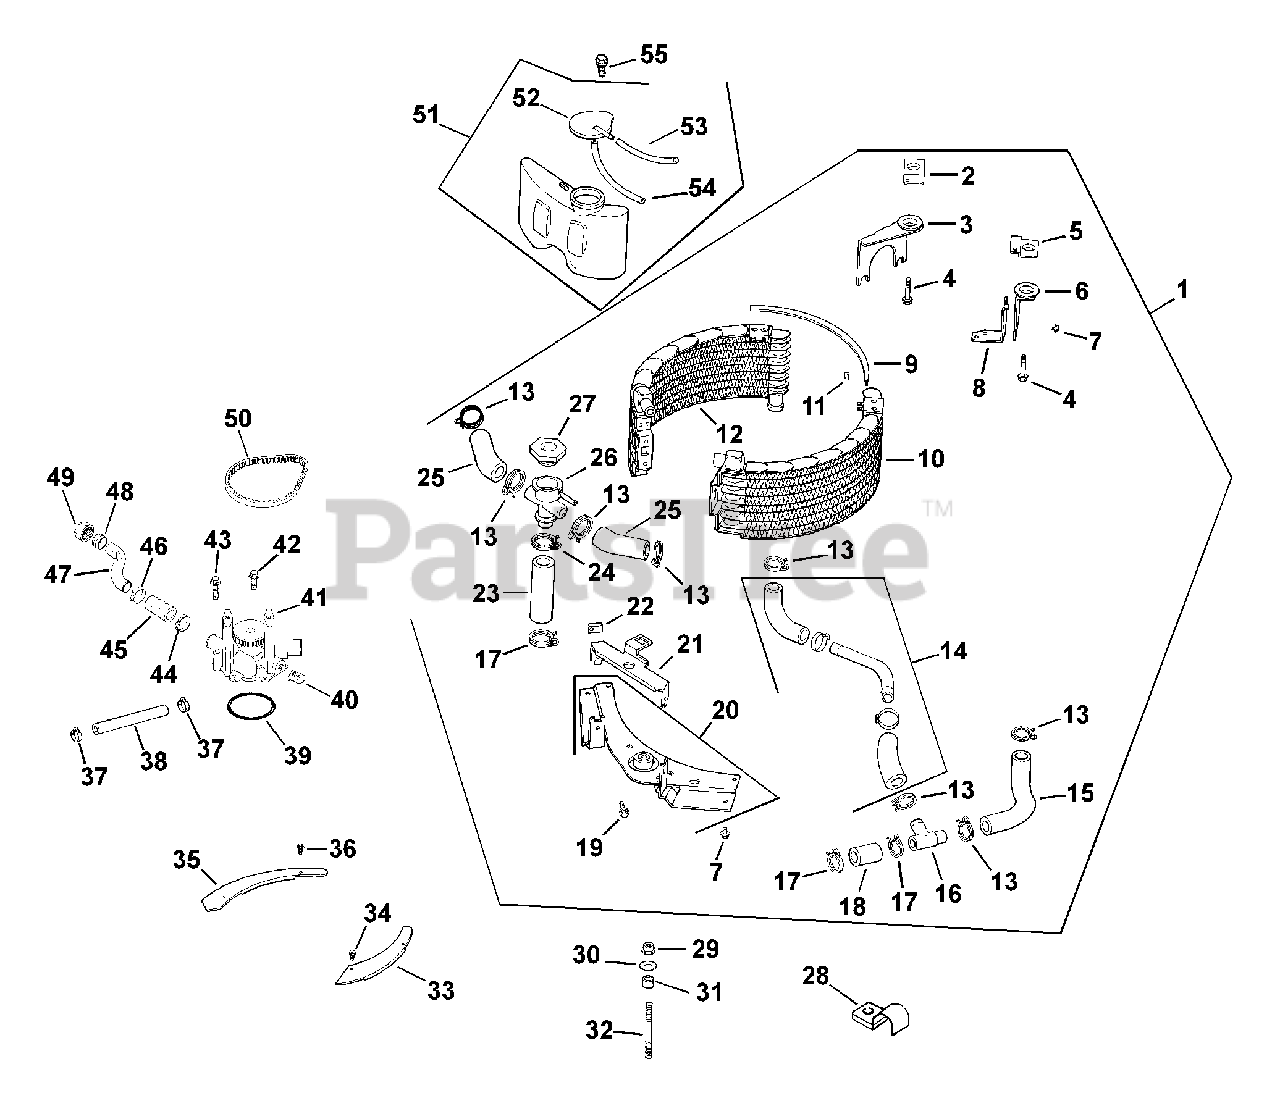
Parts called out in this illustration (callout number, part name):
1	RADIATOR ASSEMBLY - DISCONTINUED
2	BRACKET, LEFT KIDNEY
3	BRACKET, SOLENOID ATTACHING
4	SCREW, RADIATOR ISOLATOR
5	BRACKET, RIGHT KIDNEY
6	BRACKET, UPPER Z ATTACHING
7	SCREW, FLG M6X1.0X10
8	BRACKET, LOWER Z ATTACHING
9	TOP TIE BAR
10	RADIATOR CORE - (#DSC)
11	NUT, LOCK M6X1.0
12	RADIATOR CORE-DISCONTINUED
14	HOSE, OUTLET - (#DSC)
15	HOSE, OUTLET - (#DSC)
16	TEE, HOSE CONNECTOR (#DSC)
17	CLAMP, THERMOSTAT HSG OUTLET
18	HOSE, OUTLET
19	SCREW, FLG M6X1.0X16
20	BRACKET, BOTTOM ATTACHING
21	BRACKET, TOP ATTACHING
22	U CLIP - DISCONTINUED
23	HOSE, INLET - (#DSC)
24	CLAMP - DISCONTINUED
25	HOSE, INLET-DISCONTINUED
26	FILLER NECK - (#DSC)
27	CAP, RADIATOR - (#6617309S)
28	CLIP,LWR RADIATOR HOSE HALF-DISC.
29	NUT, LOCK M6X1.0
30	WASHER, FLAT 1/4"
31	SLEEVE, INTAKE MANIFOLD - DISC.
32	STUD, M6X1.0X53 - DISCONTINUED
33	PLATE, LEFT BLOCK OFF
34	SCREW, CAP M6X1.0X10
35	PLATE, RIGHT BLOCK OFF - DISC.
36	SCREW, FLG M6X1.0X12
37	CLAMP, HOSE (KM)-USE 25 237 31-S
38	HOSE, BY-PASS (12.00")
40	CONNECTOR
41	PUMP ASSEMBLY, WATER - USE 66 393 10-S
42	SCREW, FLG M6x1.0x20
43	SCREW, FLG M6X1.0X40 - DISCONTINUED
44	CLAMP - USE 25 237 32-S
45	HOSE, CROSSOVER - USE 66 755 16-S
47	TUBE, CROSSOVER - USE 66 755 16-S
50	BELT, WATER PUMP
51	TANK, OVERFLOW (BOTTLE) - DISCONTINUED
52	CAP, OVERFLOW BOTTLE - (#DSC)
53	HOSE, WATER BOTTLE - DISCONTINUED
54	HOSE, WATER BOTTLE
55	SCREW,FLG THD FRM M6X1.0X16-(#25086404S)
